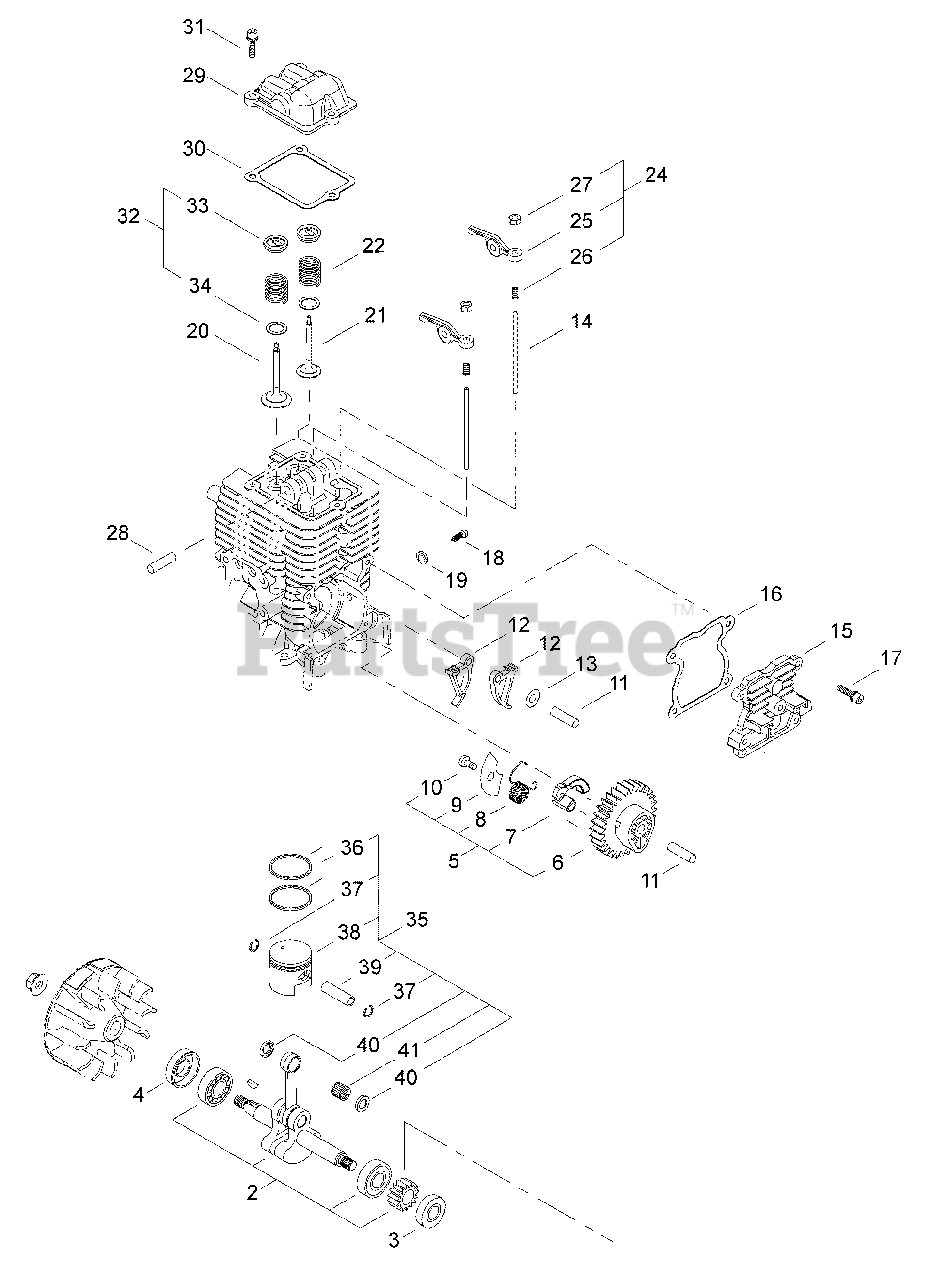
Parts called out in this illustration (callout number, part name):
2	CRANKSHAFT ASSY
3	SEAL, OIL - 12
4	SEAL, OIL
5	CAM GEAR ASSY
6	GEAR, CAM
7	WEIGHT
8	SPRING
9	COVER, PLATE
10	SCREW - 4X6 -- TAPPING
11	PIN - LOCATING
12	FOLLOWER, CAM
13	WASHER - 5
14	PUSHROD
15	COVER, CAM GEAR
16	GASKET
17	SCREW - 4X14
18	SCREW - 5
19	WASHER
20	VALVE, INTAKE
21	VALVE, EXHAUST
22	SPRING, VALVE
24	ROCKER ARM ASSY
25	ARM, ROCKER
26	SCREW, ADJUST
27	LOCKNUT, ADJUSTER
28	SHAFT, ROCKER ARM - 5X37.8
29	COVER, ROCKER ARM
30	GASKET
31	SCREW - 4X14
32	VALVE RETAINER ASSY
33	RETAINER, VALVE
34	WASHER, VALVE - 9
35	PISTON KIT
36	RING, PISTON
37	RING, RETAINING
38	PISTON
39	PIN, PISTON
40	SPACER - 9
41	BEARING, NEEDLE
